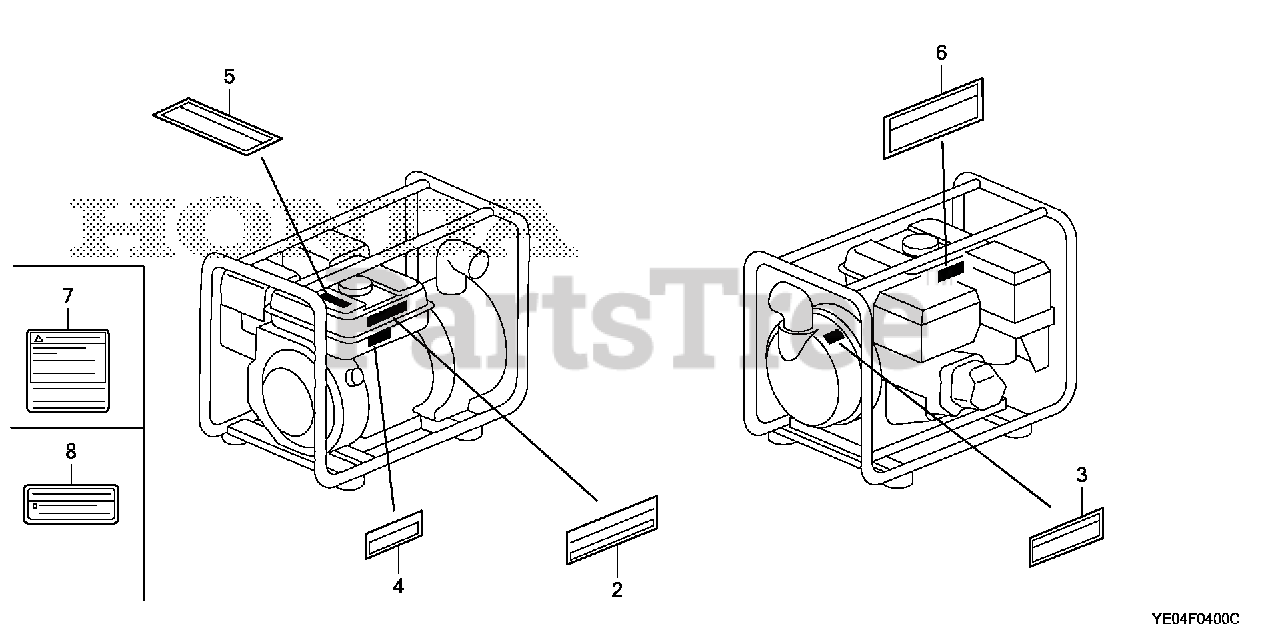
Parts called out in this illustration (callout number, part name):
2	MARK (WMP20X)
3	LABEL, WARNING (ENGLISH)
4	MARK, OIL ALERT (ENGLISH)
6	LABEL, SPARK WARNING
